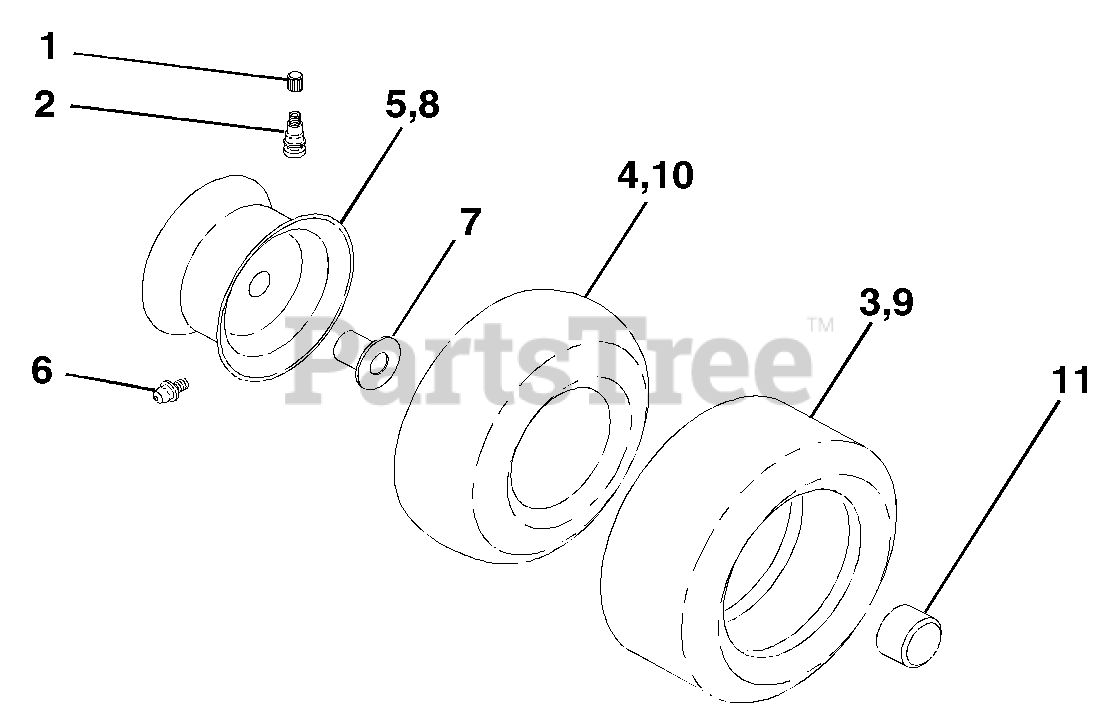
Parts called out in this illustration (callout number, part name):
1	Cap Valve Tire
2	Stem Valve
3	Tire F Ts 15 X 6 0 - 6 Service
4	Tube Front (Service Item Only)
5	Rim Asm 6"front Silver Service
6	Fitting Grease (Front Wheel Only)
7	Bearing Flange (Front Wheel Only)
8	Rim Asm 8"rear Silver Service
9	Tire R Ts 20x10-8 C Service
10	Tube Rear (Service Item Only)
11	Cap Axle Blk 1 50 X 1 00
